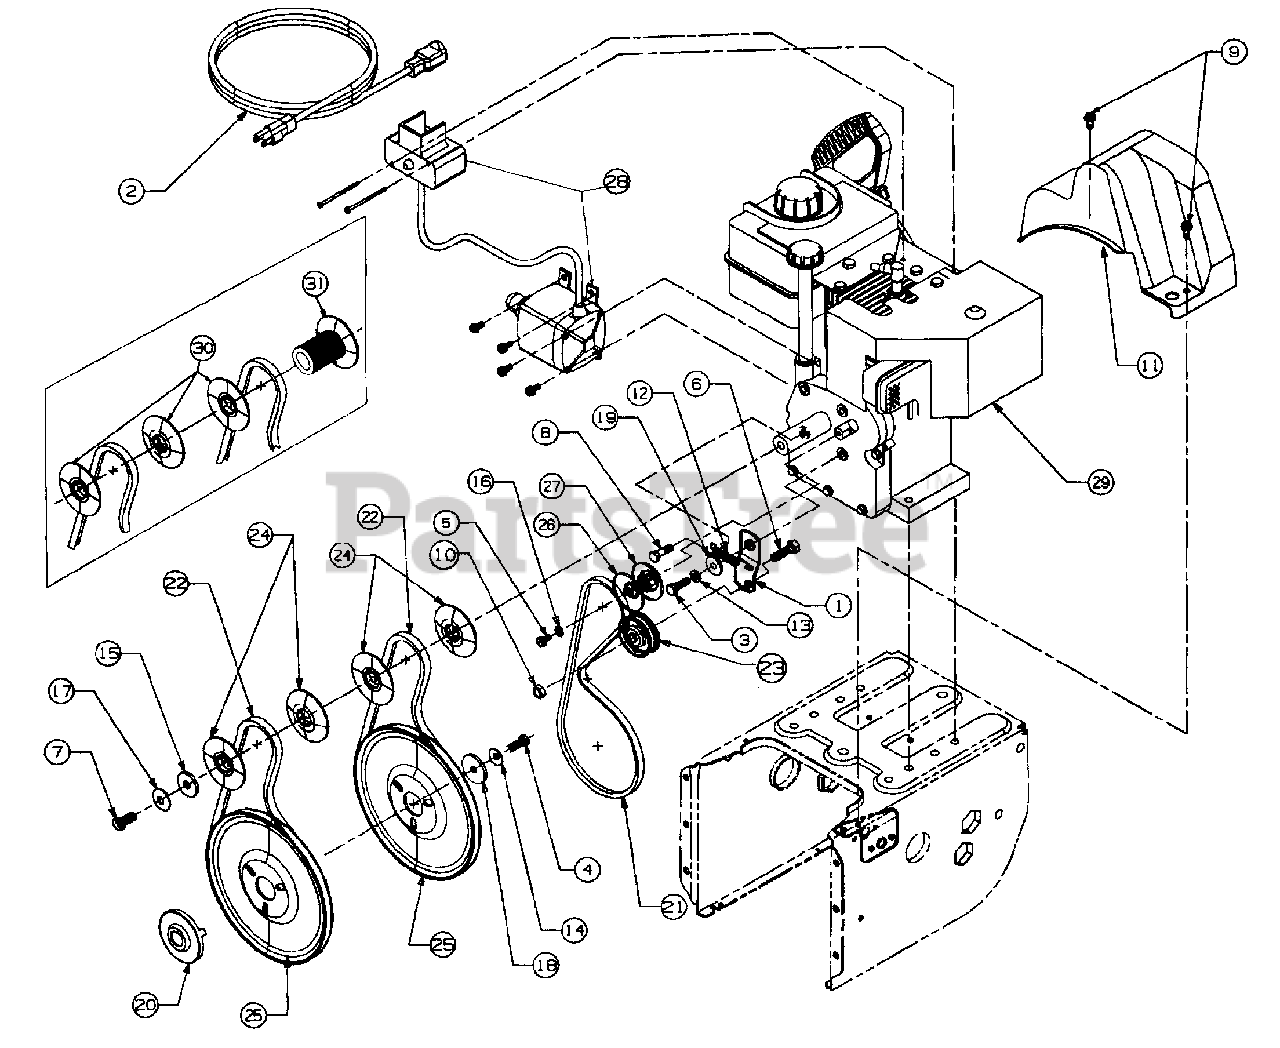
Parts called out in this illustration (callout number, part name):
3	Screw, Hex Cap 5/16-24 x 1.0 GR5
4	Screw, Hex Cap 5/16-24 x .75 GR5
5	Screw, Hex Cap, 1/4-28 x .5
6	Screw, Hex Cap, 3/8-16 x 1.25
7	Screw, Hex Cap (724E) 3/8-24 x .875 GR8
8	Screw, Hex Cap, 5/16-24 x 1.0 GR5
9	Screw, Hex Wash Hd Tapp 1/4-14 x .625
10	Nut, Hex Jam Lock, 3/8-16
11	Belt Cover
12	Spring, Extension
13	Washer, Lock, 5/16
14	Washer, Bell, .345 x .88 x .06
15	Washer, .406 x 1.25 x .157 Hdn
16	Washer, Lock 1/4
17	Washer, Bell, .39 x 1.13 x .062
18	Washer, Flat, .34 x 1.5 x .15 Hdn
19	Shoulder Spacer
20	Pulley, Adapter
21	V-Belt, 3/8 x 30
22	V-Belt, Matched, 3v x 34.9
23	Idler, Flat
24	Pulley, Half (926E and 1030E)
25	Pulley, Auger
26	Pulley Half
27	Pulley, Half
28	Starter Kit (724E)
29	Engine
30	Pulley, Half (724E)
31	Pulley, Half (724E)
